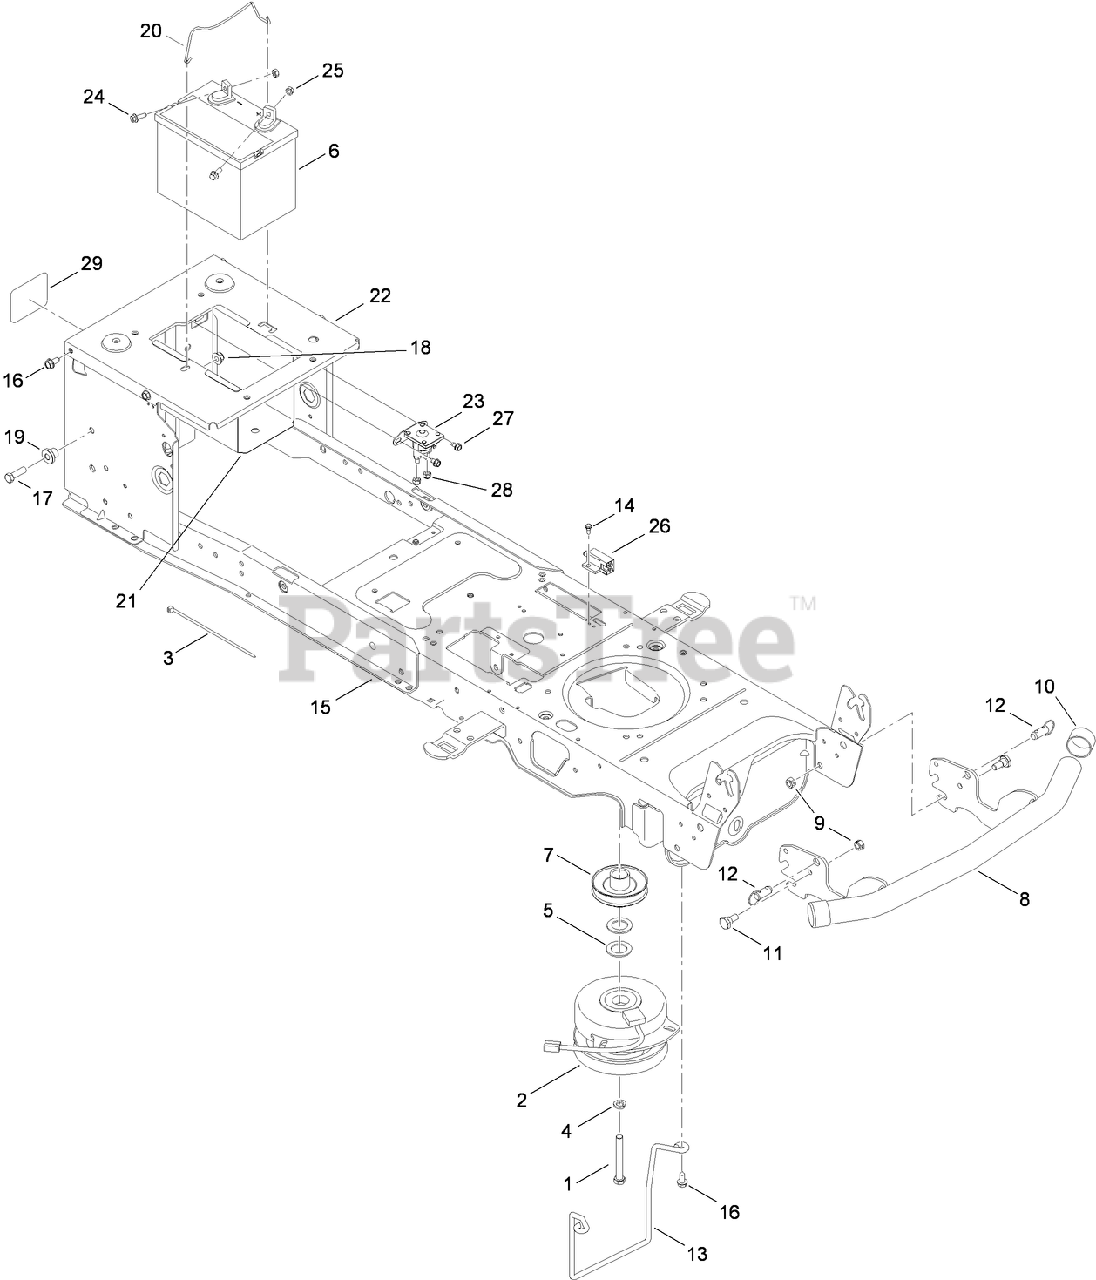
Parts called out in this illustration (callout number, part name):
1	SCREW-HH
2	CLUTCH-PTO, ELECTRIC
3	TIE-CABLE
4	WASHER-LOCK
5	WASHER-FLAT
6	BATTERY-245, CCA,DRY (FLAT TOP)
7	PULLEY-ENGINE
8	BUMPER-UNIVERSAL
9	NUT-LOCK
10	CAP-HUB
11	BOLT-SHOULDER
12	PIN-RELEASE, QUICK
13	ROD-KEEPER
14	BOLT-SHOULDER
15	LOWER FRAME ASM
16	SCREW-TAP
17	SCREW-HH
18	NUT-LOCK, FLANGE
19	SPACER-SHOULDER
20	ROD-HOLDDOWN, BATTERY
21	TRAY-BATTERY
22	BRACKET-FRAME, SEAT
23	SOLENOID-12V, 2 POST 2 TAB
25	NUT-SEMS
26	SWITCH-INTERLOCK, NO/NC
27	SCREW-TAP
28	NUT-LOCK, FLANGE
29	DECAL-RELEASE
